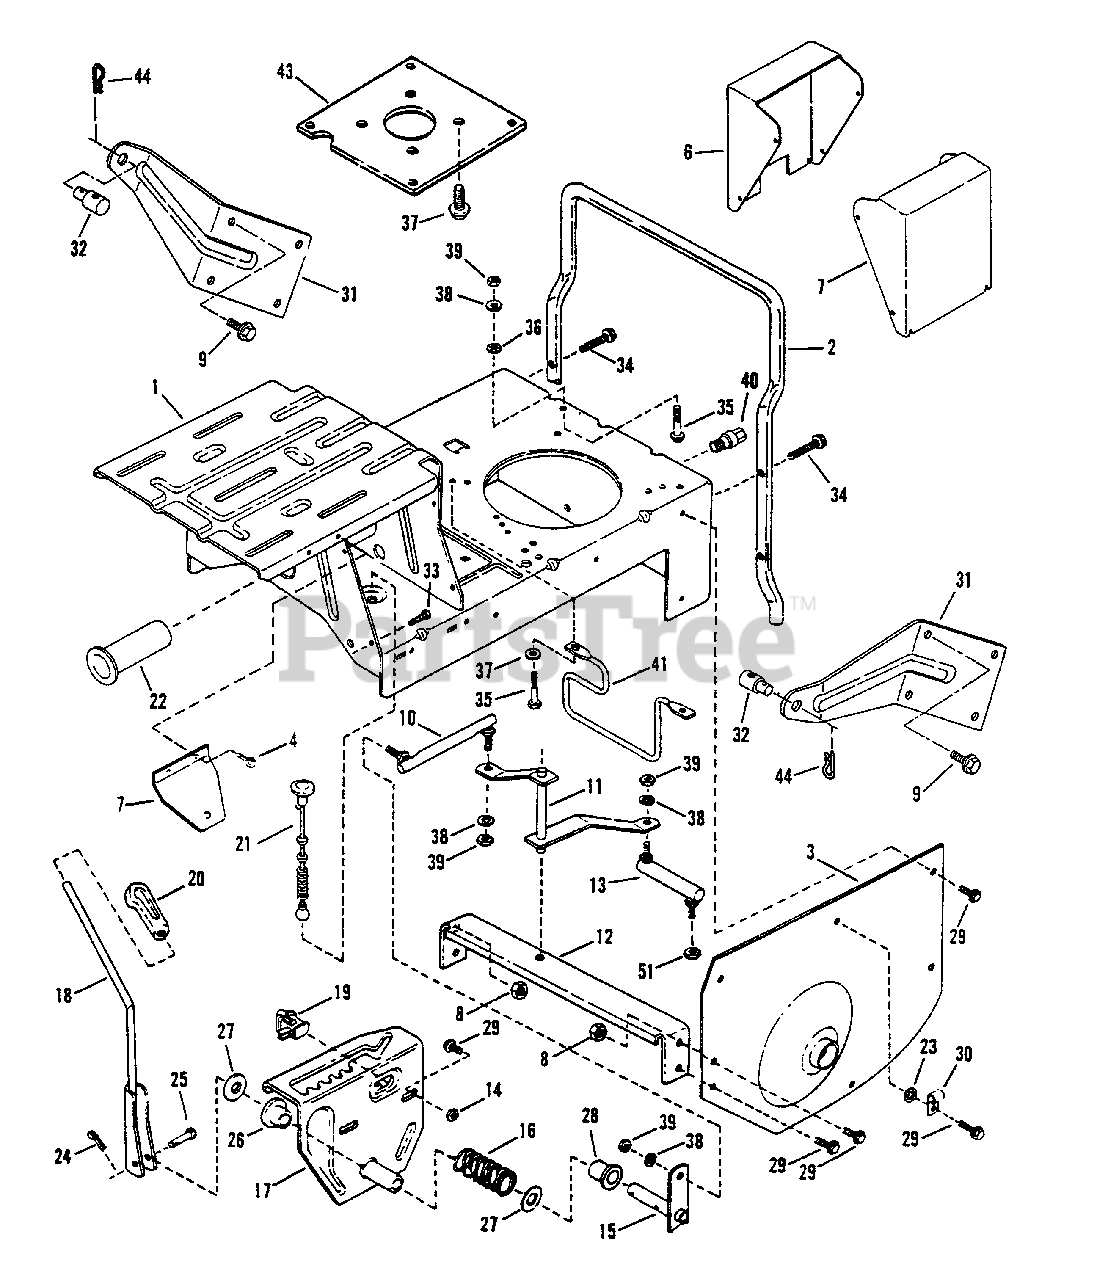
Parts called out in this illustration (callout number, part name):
1	CASE, Main
2	BUMPER, Rear
3	FENDER, Left Hand
4	SCREW, 1/4-20 x 1/2" Self-Tapping
5	COVER, Battery
6	COVER, Switch
7	PLATE, Choke
8	NUT, 5/16-18 Hex Flange Lock
9	SCREW, 5/16-18 x 3/4" Self-Tapping
10	LINK, Shift (Long)
11	ARM, Shift
12	BRACE, Cross
13	LINK, Shift (Short)
14	NUT, 5/16-18 Hex
15	ARM, Shift Handle
16	SPRING, Shift Handle
17	DETENT, Shift
18	HANDLE, Shift
19	SWITCH, Seat
20	KNOB, Shift Handle
21	WASHER, 5/16 Flat
22	BUSHING, Pilot
23	WASHER, 5/16 Internal Tooth Lock
24	PIN,3/32 x 3/4" Cotter
25	PIN, 1/4 x 1-3/4" Tapered Clevis
26	BUSHING, Nylon
27	WASHER, Thrust
28	BUSHING, Nylon
29	SCREW, 5/16-18 x 5/8" Self-Tapping
30	CLIP, Wire
31	WING, Rear Deck
32	SWIVEL
33	FASTENER, Ratchet
34	SCREW, 5/16-18 x 1-1/2" Self-Tapping
35	SCREW, 5/16-24 x 1" Hex Head Cap
36	RETAINER, 5/16 Bolt
37	SCREW, 3/8-16 x 1" Self-Tapping
38	WASHER, 5/16" Split Lock
39	NUT,5/16-24 Hex
40	ASSEMBLY, Oil Drain
41	GUIDE, Belt
43	PLATE, Engine
44	PIN, 3/32 x 1-1/2" Hair
51	NUT, 5/16-24 Hex Flange Lock
